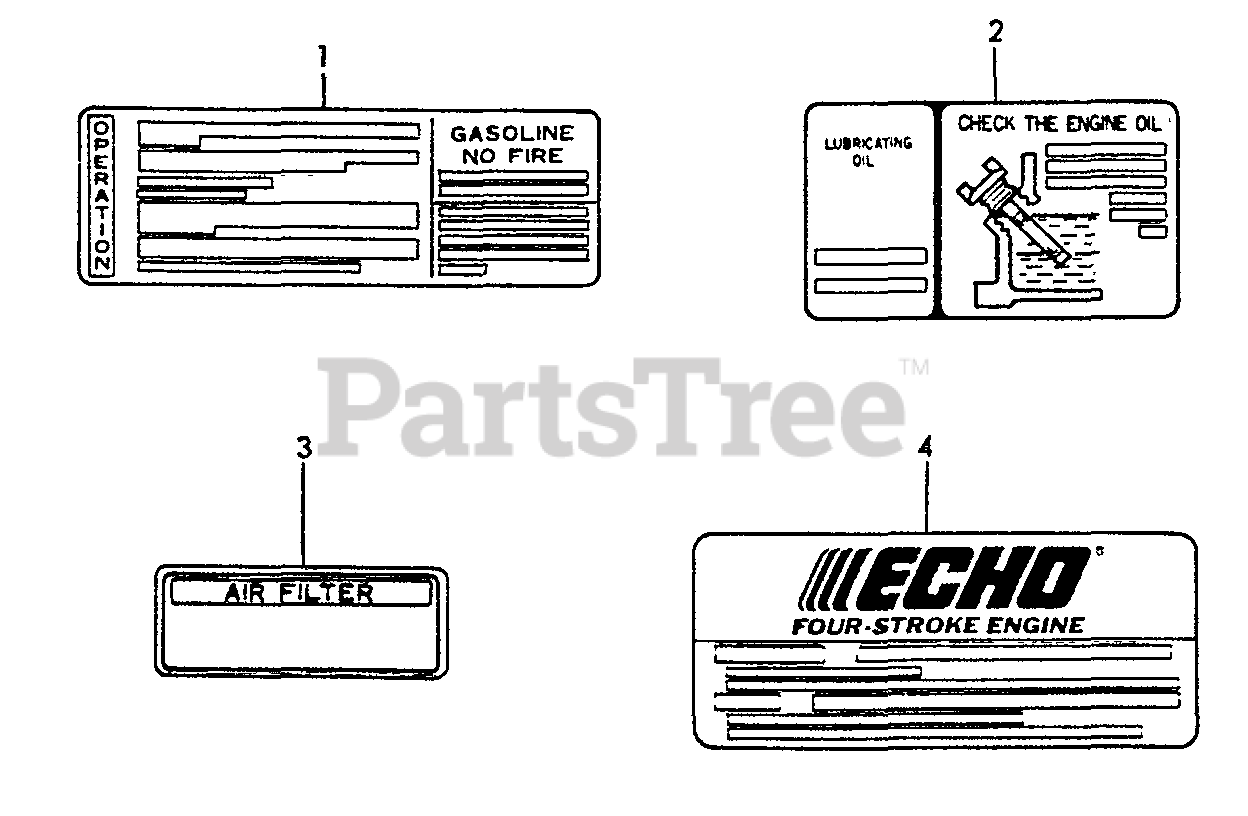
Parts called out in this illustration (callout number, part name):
1	LABEL - OPERATION
2	LABEL - OIL
3	LABEL - AIR CLEANER
4	LABEL - ECHO
